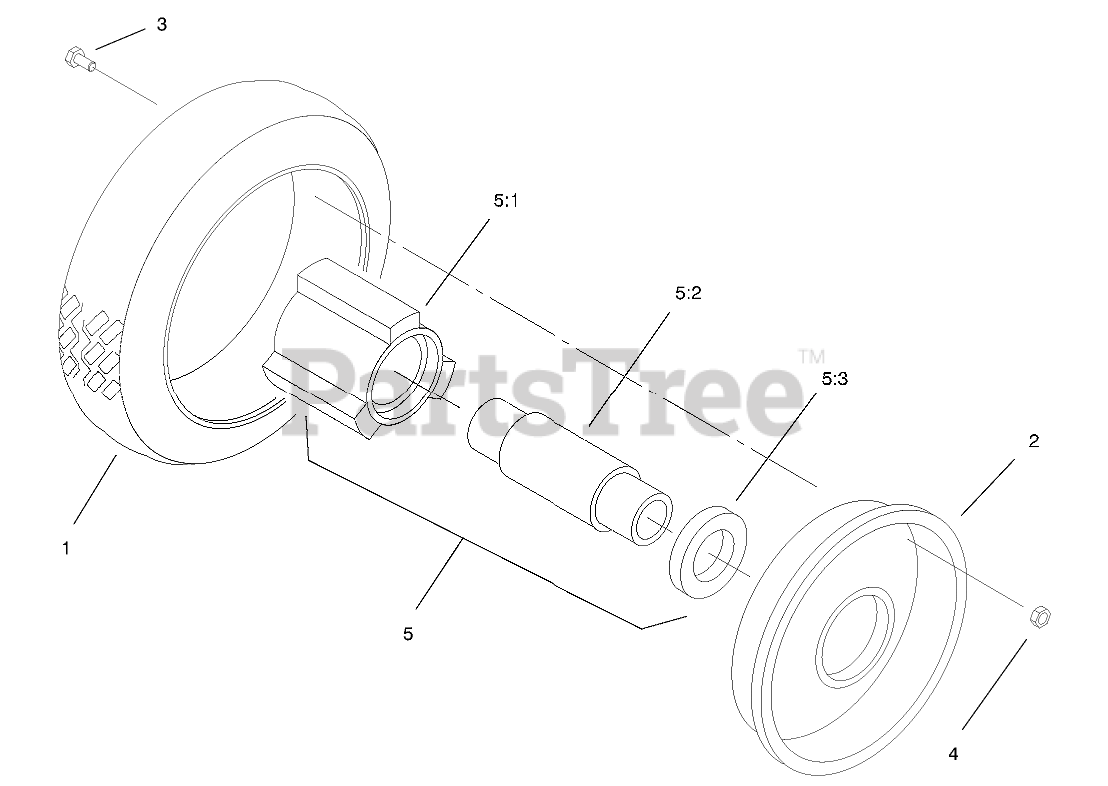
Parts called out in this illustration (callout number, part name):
2	PLATE-WHEEL, HALF
3	SCREW-HH
4	NUT-LOCK, NI
5	HUB and BEARING ASM
5:1	HUB-BEARING
5:2	SPACER-BEARING
5:3	BEARING-WHEEL
